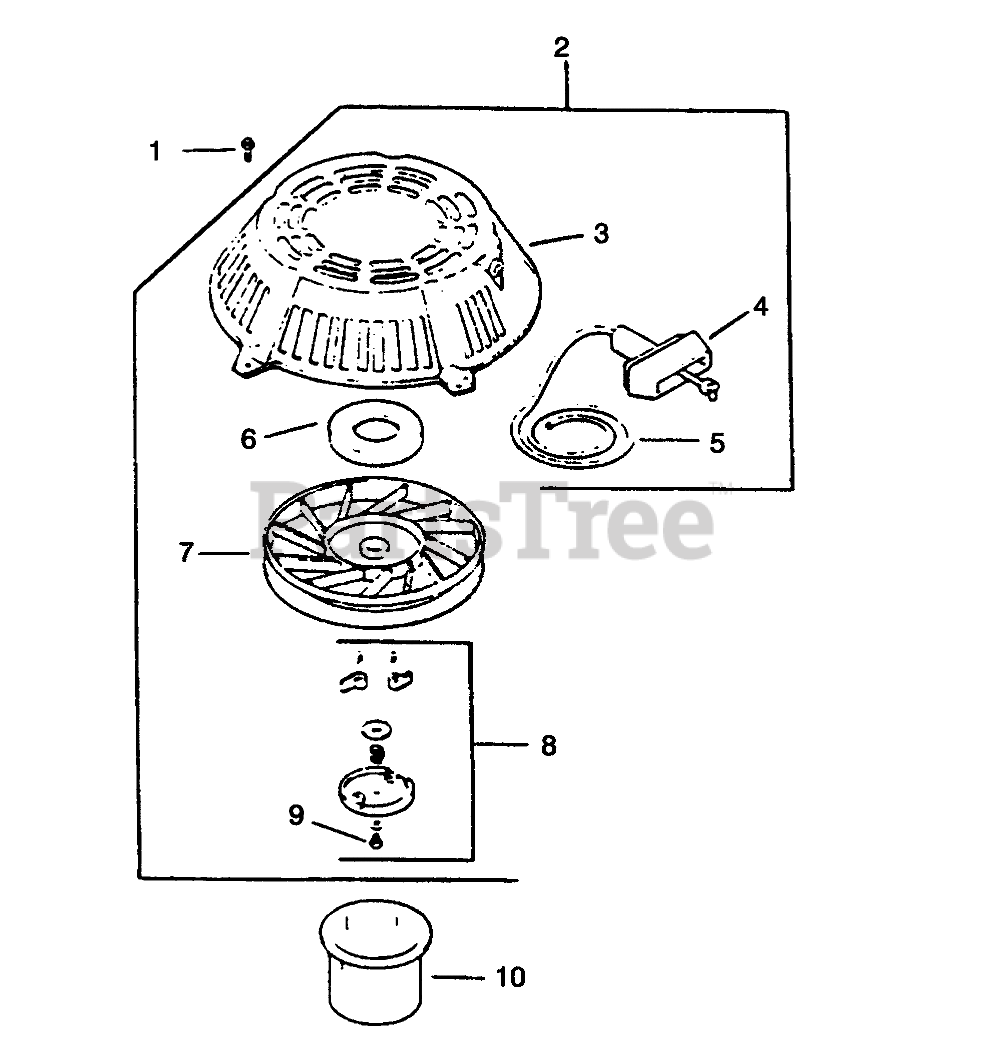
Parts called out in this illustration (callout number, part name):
1	Screw
2	Starter (Incl. Ref.#3-9)
3	Housing-Starter
4	Handle
5	Rope-Starter
6	Spring & Keeper
7	Pulley
8	Kit-Dog Replacement (Incl Ref. #9)
9	Screw-Posidrive
10	Cup-Driver
